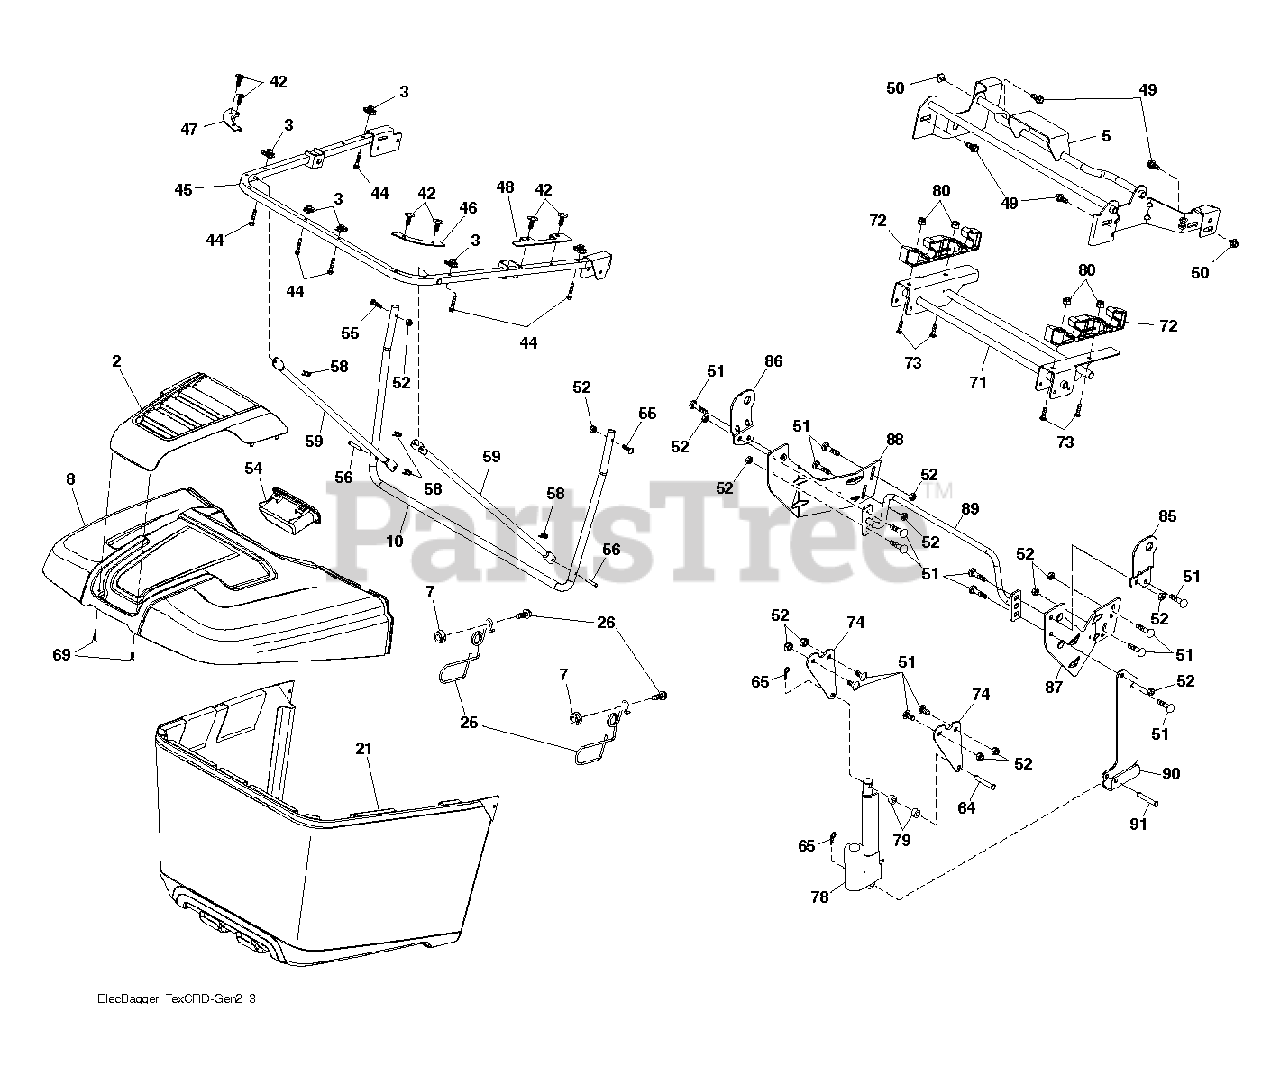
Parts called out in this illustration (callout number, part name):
2	APPLIQUE.BAGGER
3	1/4-20 U NUT
7	NUT T
10	FRAME TEX_CRD_GEN2 BAGGER FRAM
21	BAG FRAME BAGGER ASSEMBLY. HUS
25	LATCH LATCH. BAG. CRD GEN 2
26	SCREW HEX CRT
42	CLIP CHRISTMAS TREE CLIP
45	FRAME TEX_CRD_GEN2 UPPER U FRA
46	CONNECTOR RIGHT BAGGER CORNER
47	CONNECTOR LEFT BAGGER CORNER C
48	BAFFLE BAGGER SIDE CLOSE-OUT
49	BOLT, SHOULDER 5/16-18
50	BOLT, 5/16-18 X 1 3/4
51	BOLT.CARR.SQNK.5/16-18UNC.X3/4
52	NUT.71038.31-18.HEX.NYLOCK
54	HANDLE BAGGER TOP FRONT HANDLE
55	BOLT
56	PIN.CLEVIS.183
58	RETAINER CLIP PM
59	TUBE BAGGER SPREADER TUBE, TEX
65	RETAINER M
69	SCREW,#8.FLAT.HEAD.DRILL.TIP
73	BOLT.CARRIAGE.5/16-18
79	SPACER.NYLON.75" X .4375
80	NUT LOCK HEX FLANGE 5/16-18
85	BRACKET.RH.PIVOT.ELE.DUMPX431
86	BRACKET.LH.PIVOT.ELE.DUMPX431
87	BRACKET.RH.MID.SUP.BAG.TEX.CRD
88	BRACKET.LH.MID.SUP.BAG.TEX.CRD
89	WELDMENT.OFFSET.STRUT.SUP.BLAC
90	BRACKET.ELE.DUMP.ACT.BAG.X431
91	PIN.CLEVIS.(.375 X 1.25)
